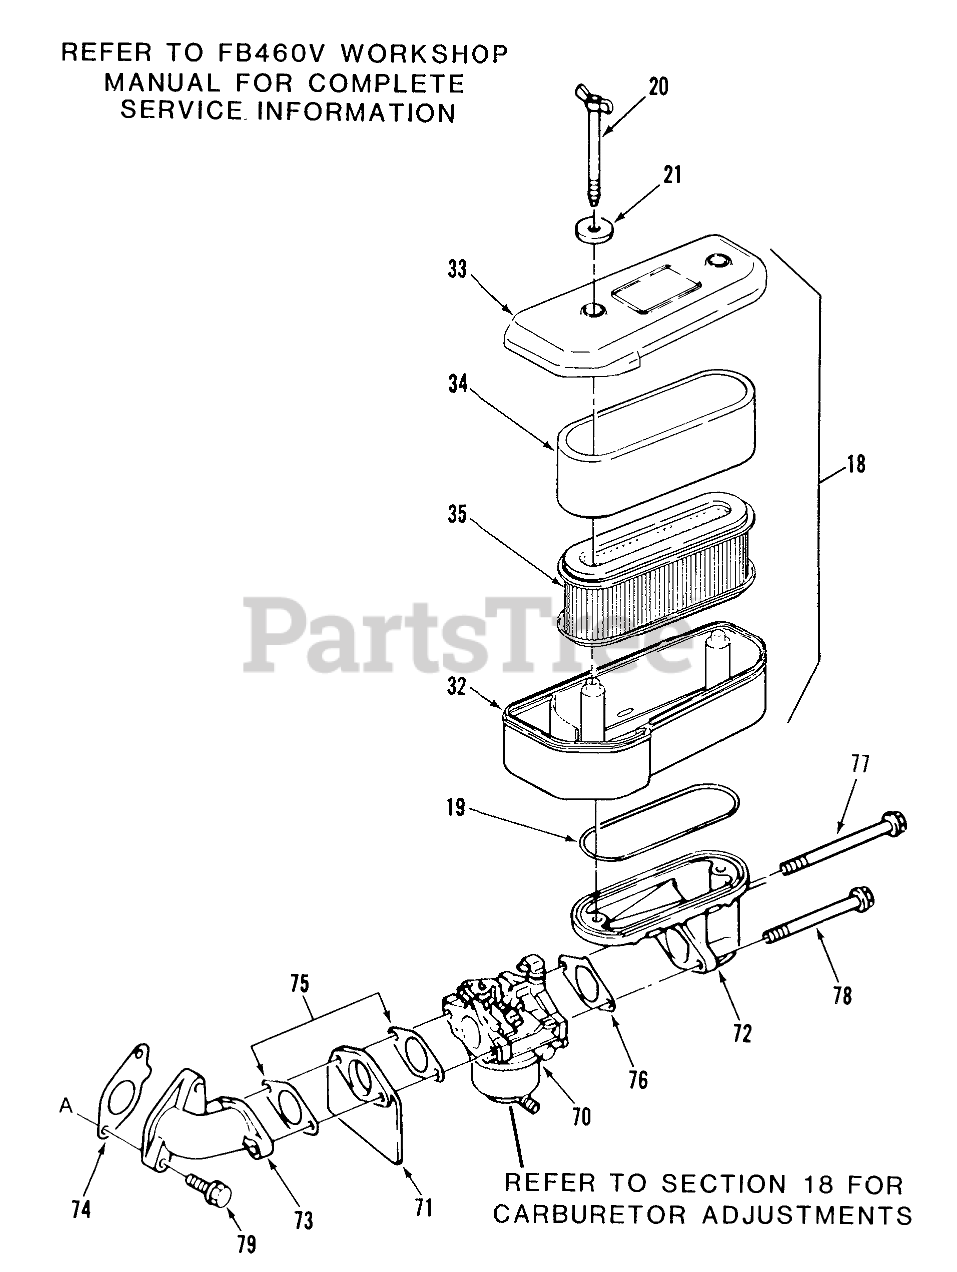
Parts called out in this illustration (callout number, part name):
18	Air Filter Assy (includes items 32, 33, 34 & 35)
19	Gasket
21	Washer
32	Air Filter Case
33	CAP-Air Filter
70	Carburetor Assy-see section 9-6 for parts breakdown
72	Pipe-Intake
73	Pipe-Intake
74	Gasket
75	Gasket
76	Gasket
79	Bolt 8x25
